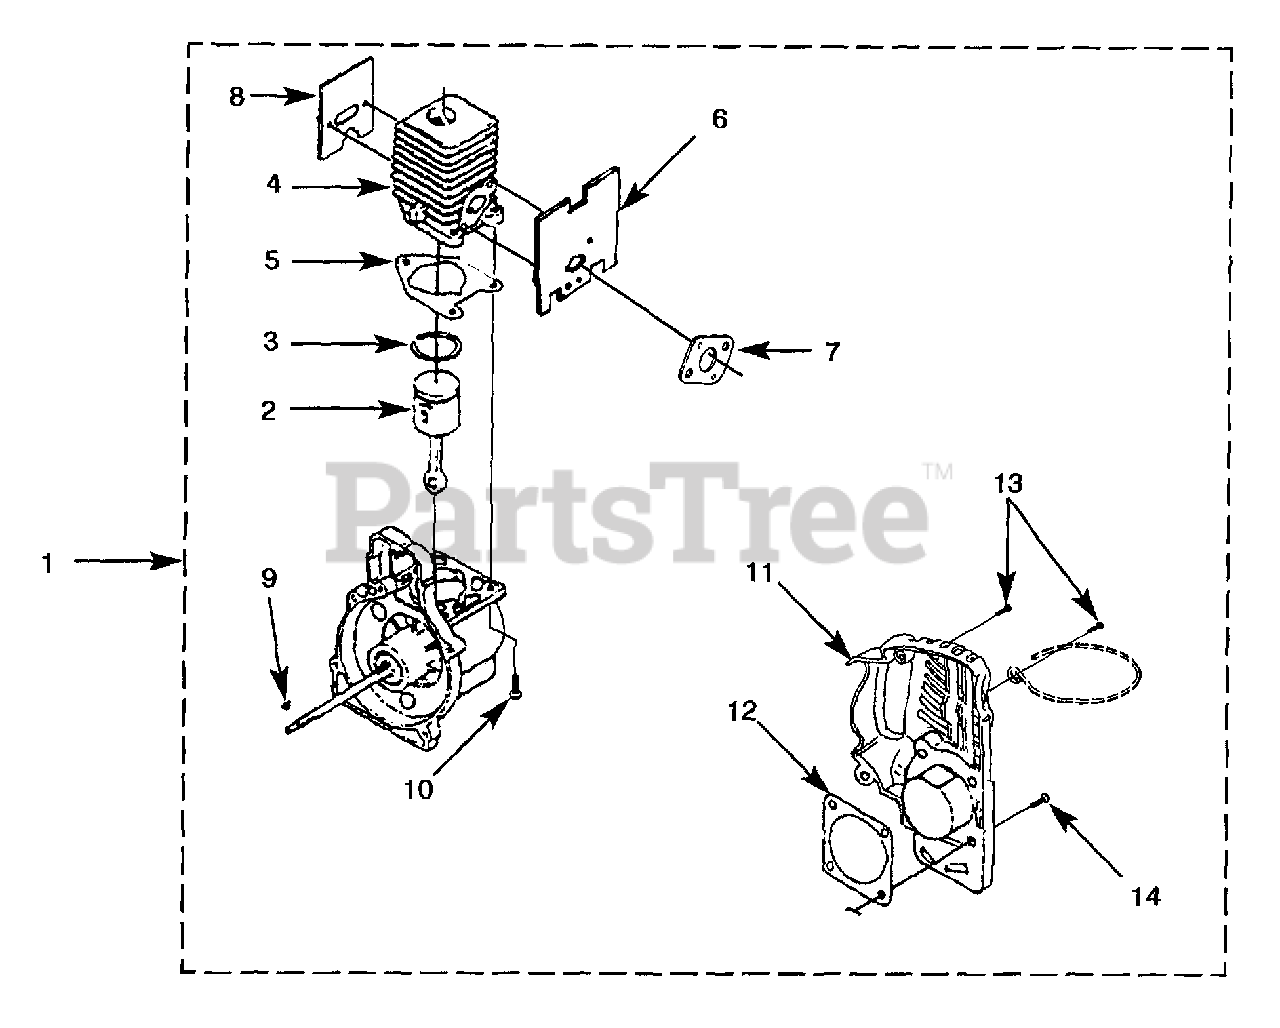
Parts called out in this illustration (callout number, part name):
1	SHORT BLOCK
2	21CC PISTON & ROD
3	RING-Piston
4	25CC CYLINDER KIT
5	GASKET-Cylinder
6	GASKET-Heat Dam
7	GASKET-Carburetor
8	GASKET-Muffler
9	KEY-Woodruff
10	SCREW-Sems. (12-24 X 3/4")
11	CRANKCASE COVER
12	GASKET-Crankcase Cover
13	SCREW-Plastite (#10-24 X 3/4")
14	SCREW-Sems (10-24 X .910)
